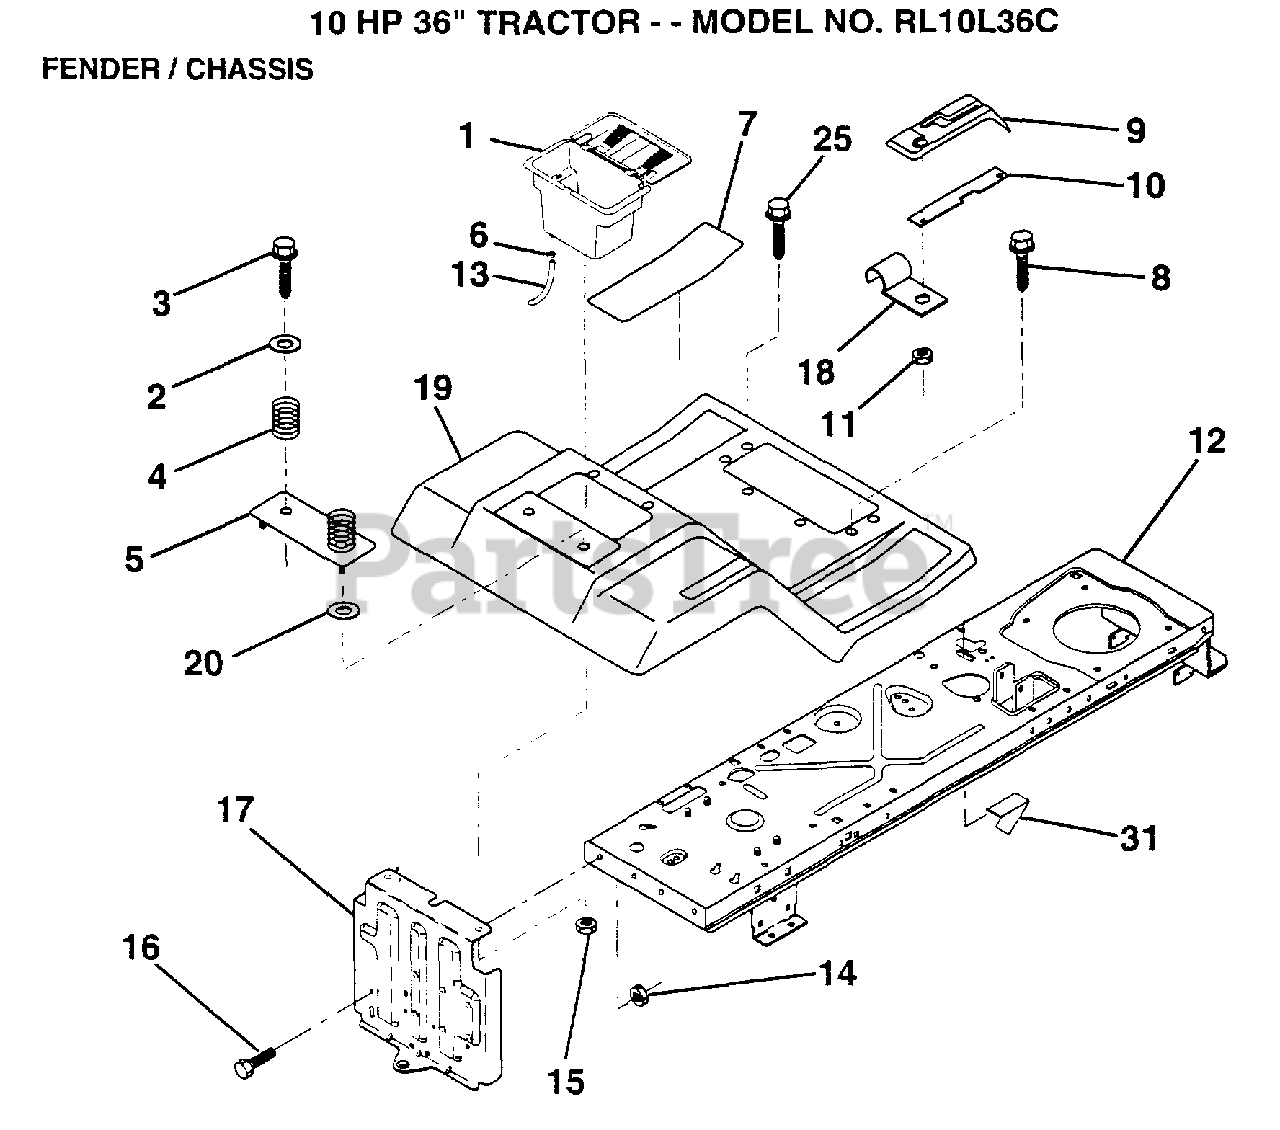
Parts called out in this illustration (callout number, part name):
2	WASHER
3	SCREW
4	SPRING COMPRESSIO
5	"PLATE, BATTERY"
6	HOSE CLAMP T
7	PAD FOOTREST
8	SCREW
9	CONSOLE SHFT 4SP
10	PLATE LOCK SHIFT
11	NUT
13	TUBE T
14	NUT
15	NUT
16	BOLT
17	DRAWBAR ASM LR
18	"CLIP,INSULATOR"
19	FENDER/FOOT MS419
25	SCREW TI
